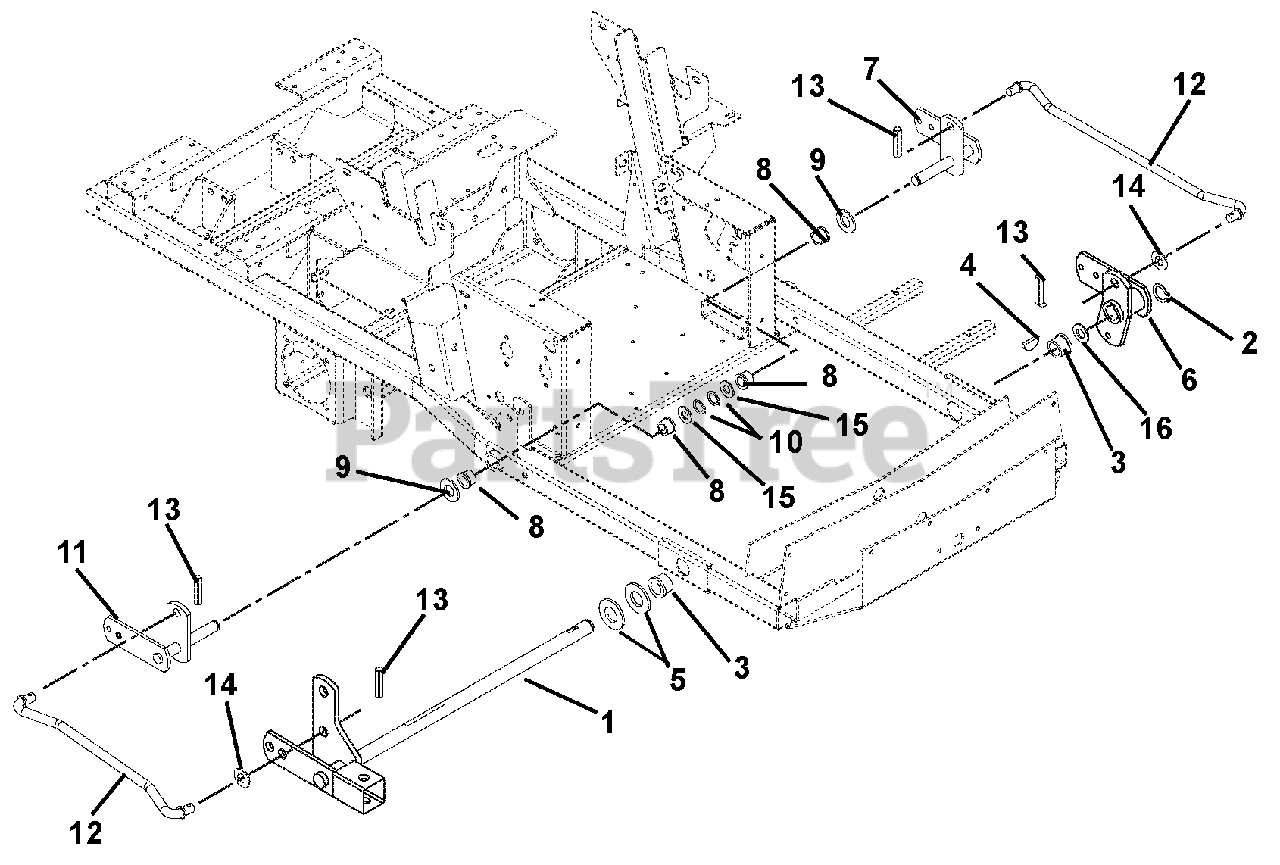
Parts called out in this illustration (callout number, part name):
1	Lift, Mower
2	Ring, Retaining External 1.00 x .078
3	Bushing, Flange Nylon 1.02 x 1.385 x .75 x 1.75
4	Key, Woodruff .25 x 1.00
5	Washer, Flat Steel 1.062 x 2.00 x .134
6	Weldment, Lift Arm-Front
7	Weldment, Rear Lift Arm-Left Hand
8	Bushing, Flange Nylon .762 x 1.0 x .58 x 1.48
9	Washer, Hardened Steel .758 x 1.23 x .031
10	Ring-Retaining-External .689 x .077
11	Weldment, Rear Lift Arm- Right Hand
12	Rod, Lift Assist 19.35"
13	Pin, Roll .25 x 1.25 Stainless Steel
14	Washer, Flat Steel .630 x 1.25 x .062
15	Washer, Flat Steel .755 x 1.25 x .125
16	Washer, Hardened Thrust 1.00 x 1.55 x .03
